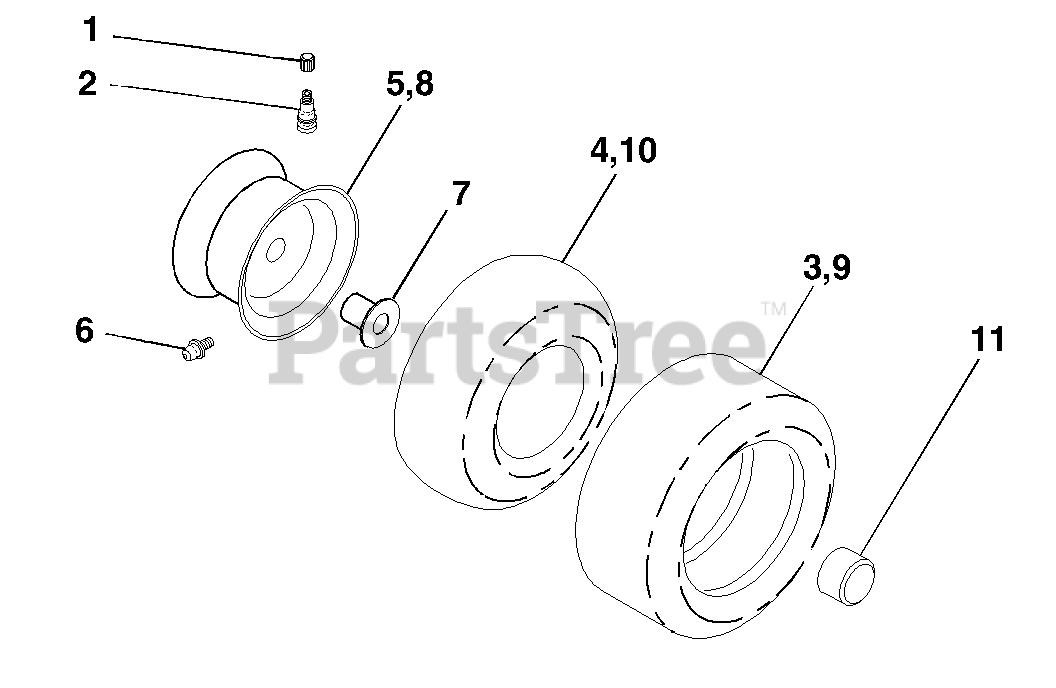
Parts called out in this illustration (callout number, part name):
1	Cap, Tire valve
2	Stem, Valve
3	Tire, Front
4	Tube, Front
5	Rim assembly, 6"front
6	Fitting, Grease
7	Bearing, Flange
8	Rim assembly, 8" rear
10	Tube, Rear
11	Cap, Hub Axle
